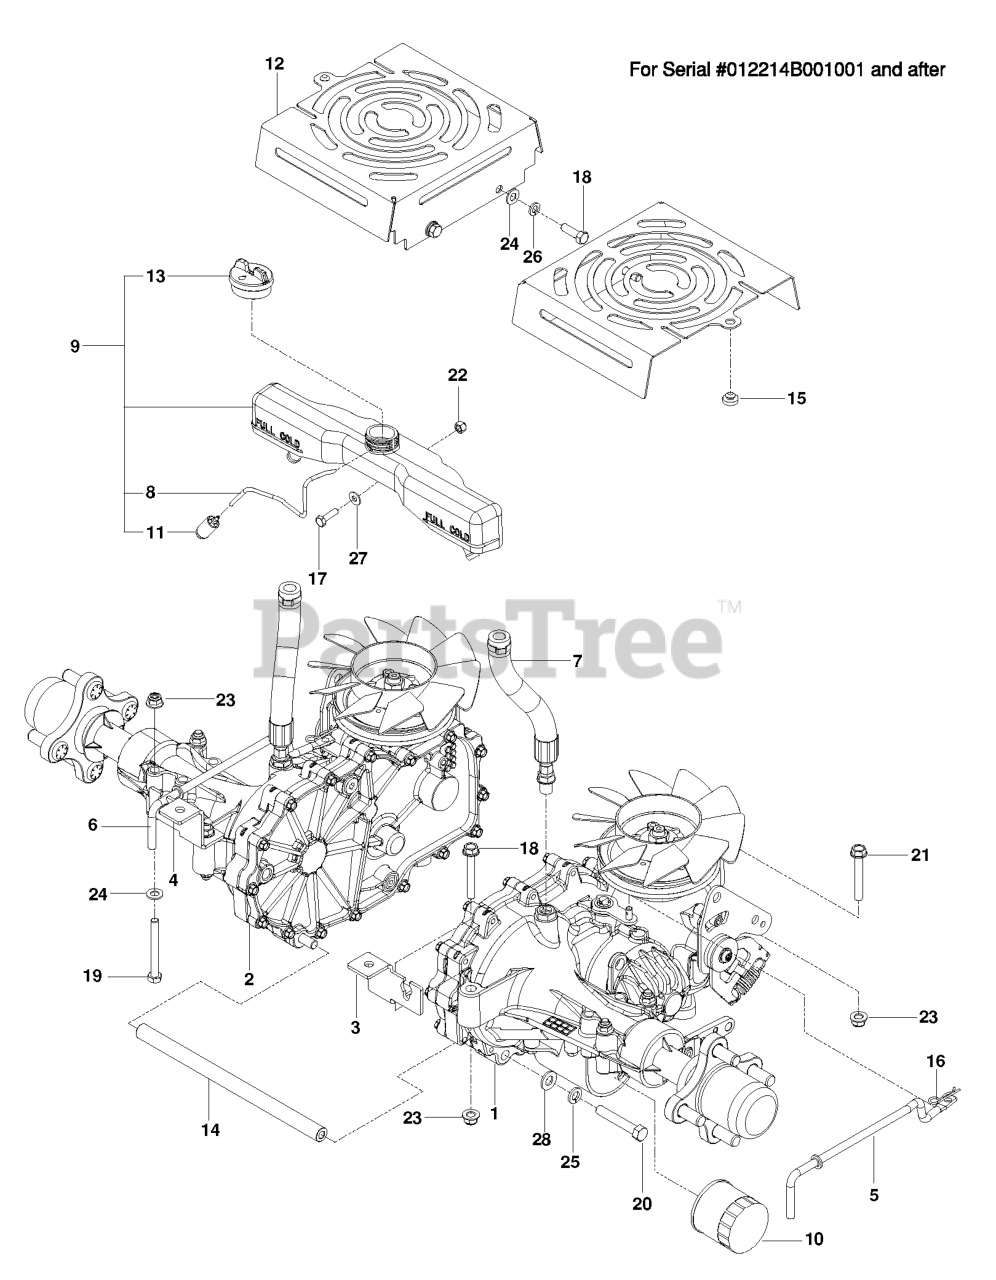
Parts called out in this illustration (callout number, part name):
1	HG_TRANS ZT-3100 LT
2	HG_TRANS ZT-3100 RT
3	BRACKET.TRANS.LT.BLACK
4	BRACKET, TRANS, RT BLACK
5	LINKAGE, LEFT BYPASS
6	LINKAGE, RIGHT BYPASS
7	HOSE EXPANSION HYDRO
9	TANK EXPANSION W/CAP
10	HG_FILTER, ZT4800 52114
11	FUEL PICK-UP ASSY
12	SHIELD, FAN, BLK
13	CAP EXPANSION W/SEAL
14	TUBE, SPACER, 3400
15	GROMMET, BUMPER
16	HAIRPIN #2
17	HCS 1/4-20X7/8 GR5
18	HCS 5/16C X 1
19	HCS 5/16C X 2-3/4
20	HCS 3/8-16X2-1/4 LOC PATCH GR8
21	HHFS 5/16-18 X 2.25 GD 5
22	NUT.1/4-20.HEX.NYLOC.ZD
23	5/16-18 NYLOC FLANGE NUT
24	FLAT WASHER 5/16 SAE
25	SLW 3/8 STD
26	WASHER.LOCK.HVY.HLCL.SPR.5/16
27	WASHER 1/4 SAE
28	WASHER 3/8 SAE FLAT
